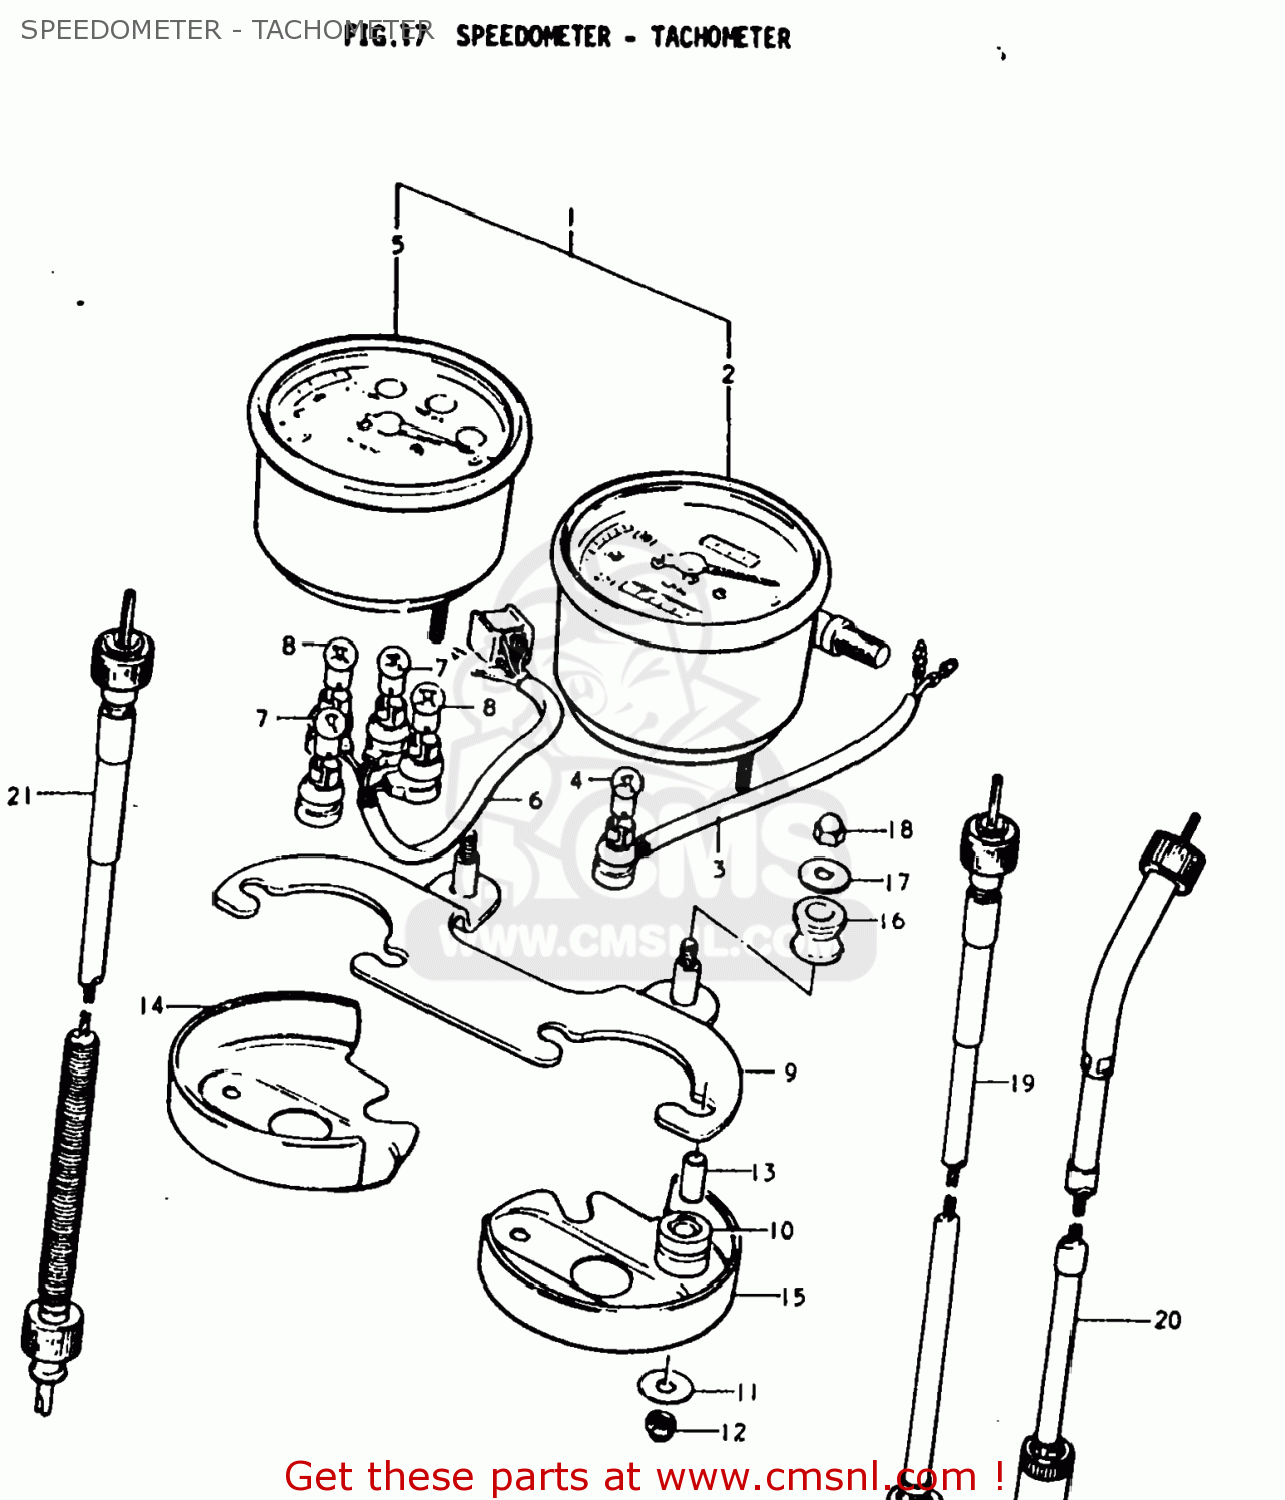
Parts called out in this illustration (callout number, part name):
1	SPEEDOMETER ASSEMBLY
2	SPEEDOMETER ASSEMBLY
3	SOCKET,SPEEDOMETER
4	BULB(6V/3W)
5	METER,TACHOMETER
6	SOCKET,TACHOMETER
7	BULB(6V/3W)
8	BULB(6V1.7W,STANLEY,A61A)
9	BRACKET,METER
10	CUSHION
11	WASHER,METER
12	NUT
13	SPACER,METER
14	COVER,METER,UNDER
15	COVER,METER,UNDER
16	CUSHION
17	WASHER
18	NUT
19	CABLE ASSEMBLY,SPEEDOMETER
20	CABLE ASSEMBLY,SPEEDOMETER
21	CABLE ASSEMBLY,TACHOMETER
